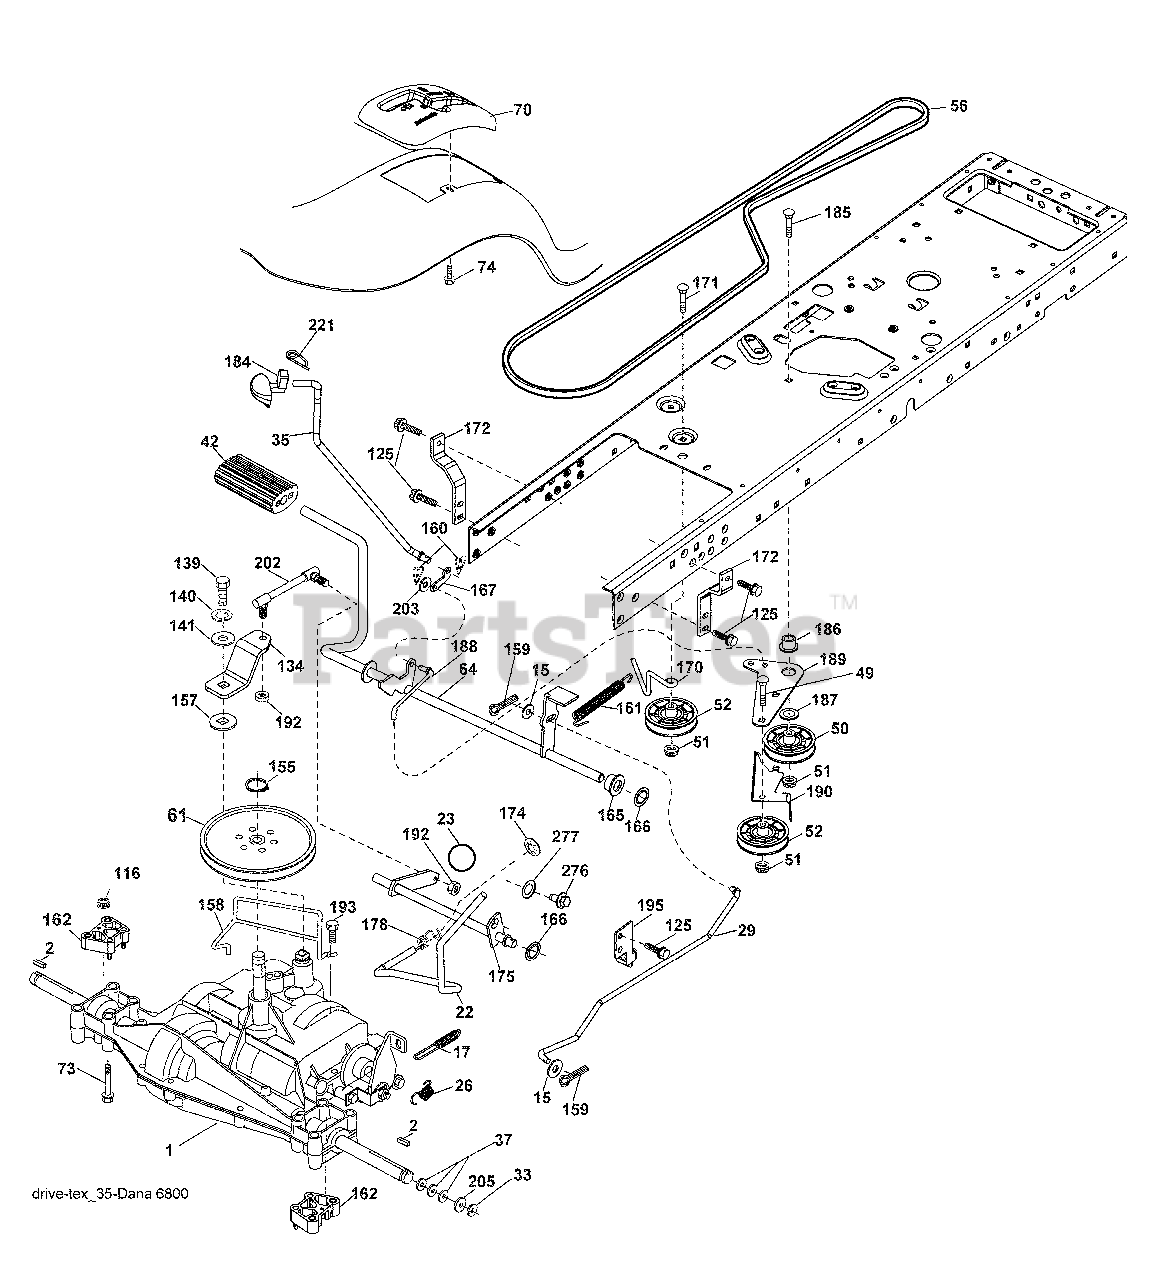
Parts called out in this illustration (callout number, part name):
2	Key Square
15	Washer 13/32 x 13/16 x 16 Ga.
17	Spring, Brake
26	Spring Brake Return
29	Rod, Brake
35	Rod, Brake, Park
37	Washer 25/32 x 1-1/4 x 16 Ga.
42	Cover, Foot Pedal
50	Pulley Idler Flat
51	Lock Nut 3/8-16
52	Idler V-Groove 910" Offset
56	V-Belt, Drive
61	Pulley transaxle
64	Shaft Asm. Pedal Brake Control
70	Console
73	Bolt Hex Flghd 5/16-18 x 3.0 Gr. 5
74	Screw 1/4 x 1/2
116	Nut Lock Hex Flange 5/16-18
125	Screw 5/16-18 x 3/4
139	Bolt 1/4-28 unf Gr. 8 w/Patch
140	Washer Lock Hvy Helical 1/4
141	Washer 9/32 x 3/4 x 10 Ga.
155	Ring Retainer
157	Washer Plate Shift
158	Belt Keeper
159	Pin Cotter 1/8 x 3/4
160	Retainer Clip
161	Spring, Return, Clutch
162	Spacer Trans.
165	Busing Shaft Brake Hand Control
166	Nut Push .625
167	Latch Brake Parking
170	Keeper Belt Centerspan
171	Bolt
172	Strap Torque LH
175	Shaft Asm. Shift
178	Spring Shift
184	Handle Parking
185	Bolt
186	Spacer Retainer
187	Washer
188	Link Clutch Ground Drive
189	Bellcrank Ground Drive
190	Keeper Bellcrank Ground Drive
192	Nut Lock Center 1/4-28 Fnthd
193	Screw 5/16-18 x 3/4
195	Bracket Brake Rod
202	Link Transaxle
203	Washer 11/32 x 11/16 x 16 Ga.
205	Washer 25/32 x 1-5/8 16 Ga.
221	Retainer Spring Clip Handle
276	Bolt Fin Hex 7/16-14 x 1 Gr. 5
277	Washer Serrated
